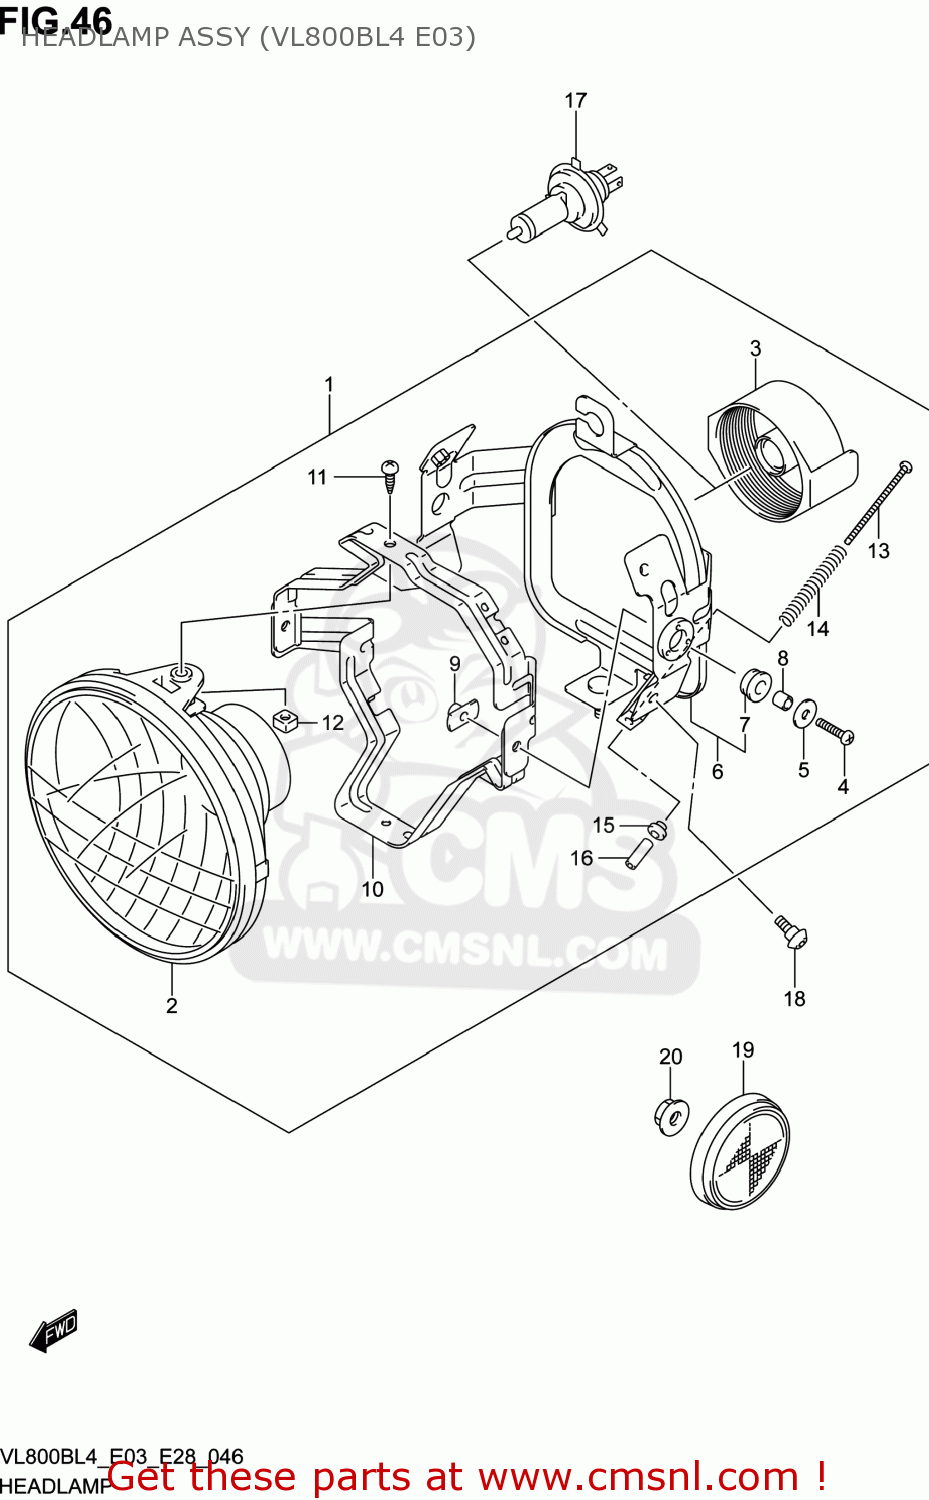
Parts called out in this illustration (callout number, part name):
1	HEADLAMP ASSY
2	UNIT
3	COVER,SOCKET
4	SCREW
5	WASHER(5.5X18X1)
6	BRACKET
7	CUSHION
8	SPACER
9	NUT
10	BRACKET
11	SCREW(5X16)
12	NUT
13	SCREW,ADJUSTER
14	SPRING,ADJUSTER
15	NUT,HEADLAMP ADJUST
16	COVER
17	BULB(12V60/55W,H4)
18	BOLT(6X12)
19	REFLEX REFLECTOR ASSY,FR SIDE
20	NUT
